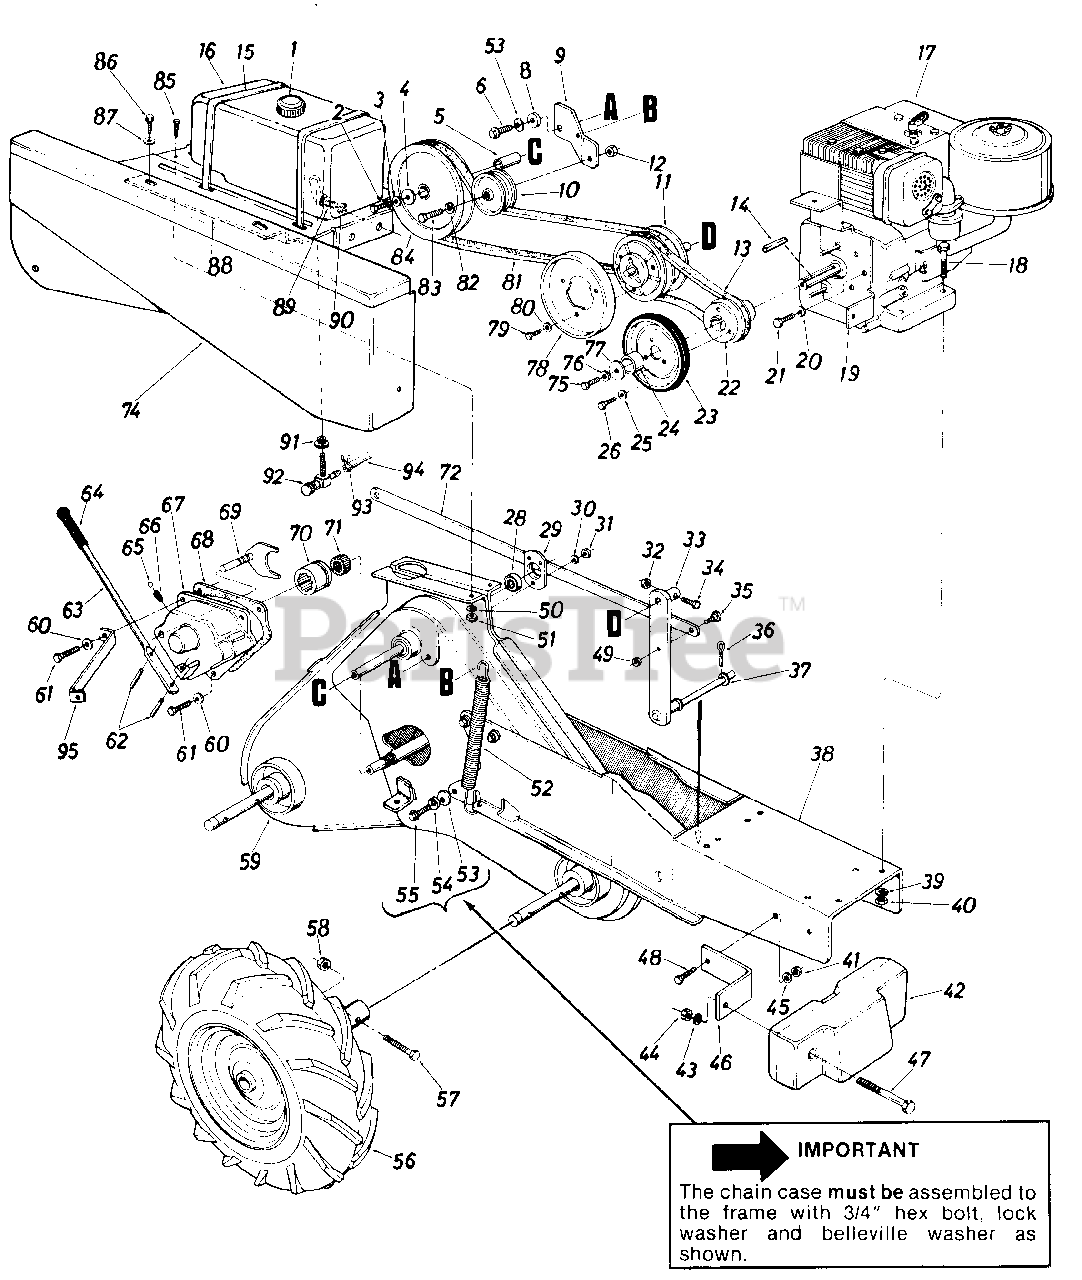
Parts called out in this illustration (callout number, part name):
2	Hex L-Scr. 5/16-24 x .75" Lg.
3	L-Wash. 5/16" I.D.
4	Fl-Wash. 5/16" I.D.
5	Spacer .637" I.D. x .78" O.D. x 1.44" Lg.
6	Hex Bolt 3/8-24 x 1.25" Lg.
8	Shoulder Spacer
9	Idler Bracket
10	Fl-Idler 2.75" Dia.
11	Variable Speed Ass'y.
12	Hex Ins. L-Nut 3/8-16 Thd.
13	"V"-Belt 5/8" x 27.0" Lg.
14	Sq. Key 1/4" x 1.50" Lg.
15	Cable Tie
17	Engine
18	Hex Bolt 5/16-18 x 1.75" Lg.
19	Belt Cover Support Ass'y.
20	Internal L-Wash. 1/2" I.D.
21	Hex Bolt 1/2-20 x .75" Lg.
22	Engine Pulley Ass'y.
23	Friction Wheel Ass'y.
25	L-Wash. 5/16" I.D.
26	Hex Bolt 5/16-18 x .50" Lg.
28	Ball Bearing
29	Bearing Housing 1-3/8" O.D.
30	L-Wash. 1/4" I.D.
31	Hex Nut 1/4-28 Thd.
32	Hex Ins. L-Nut 1/4-20 Thd.
33	Variable Speed Brkt. Ass'y.
34	Hex Bolt 1/4-20 x 1.25" Lg.
35	Shld. Bolt 1/2" Dia. x .25" Lg.
36	Cotter Pin 1/8" Dia. x 1.0" Lg.
37	Fl-Wash. .686" I.D. x 1.25" O.D.
38	Frame Ass'y.
39	L-Wash. 5/16" I.D.
40	Hex Nut 5/16-18 Thd.
41	Hex Cent. L-Nut 3/8-24 Thd.
43	Fl-Wash. .50" I.D. x 1.0" O.D.
44	Hex Nut 1/2-13 Thd.
45	L-Wash. 3/8" I.D.
46	Weight Mtg. Brkt.
47	Hex Bolt 1/2-13 x 4.50" Lg.
48	Hex Bolt 3/8-24 x 1.00" Lg.
49	Hex Ins. L-Nut 3/8-16 Thd.
50	L-Wash. 1/4" I.D.
51	Hex Cent. L-Nut 1/4-28 Thd.
52	Spring Idler Bracket
53	Belleville Wash. 3/8" I.D.
54	L-Wash. 3/8" I.D.
55	Hex Self-Tap Scr. 3/8-16 x .75" Lg.
56	Wheel Ass'y. Comp. - R.H.
57	Hex Bolt 3/8-24 x 1.25" Lg.
58	Hex Ins. L-Nut 3/8-24 Thd.
59	Chain Case Ass'y. Comp.
60	L-Wash. 5/16" I.D.
61	Hex Tap Tite 5/16-18 x .75" Lg.
62	Headed Spiral Pin 3/16 x 13/16" Lg.
63	Engagement Lever
65	Ball Detent .250" Dia.
66	Compression Spring
67	Shift Housing - R.H.
68	Gasket - Shift Housing
69	Shift Yoke Ass'y. - R.H.
70	Clutch Dog
71	Clutch Dog Driver
72	Control Brkt.
74	Shroud Belt Cover
75	Hex Bolt 7/16-20 x 1.00" Lg.
76	L-Wash. 7/16" I.D.
77	Fl-Wash. .44 I.D. x 1.38" O.D.
78	Friction Disc
79	Hex Bolt 1/4-28 x .50" Lg.
80	L-Wash. 1/4" I.D.
81	"V"-Belt 5/8" x 51" Lg.
82	L-Wash. 3/8" I.D.
83	Hex Bolt 3/8" x 1.50" Lg.
84	Input Pulley - Chain Case
85	Hex Bolt 1/4-28 x .62" Lg.
86	Hex Wash. Hd. Self-Tap Scr.
87	Fl-Wash. 1/4" I.D.
88	Tank Mounting Brkt.
89	Hex Bolt 5/16-18 x .75" Lg.
90	L-Wash. 5/16" I.D.
91	Bushing - Gas Line
92	Shut-Off Valve
93	Clamp Gas Line
94	Gas Line 14 1/2" Lg.
95	Brace
